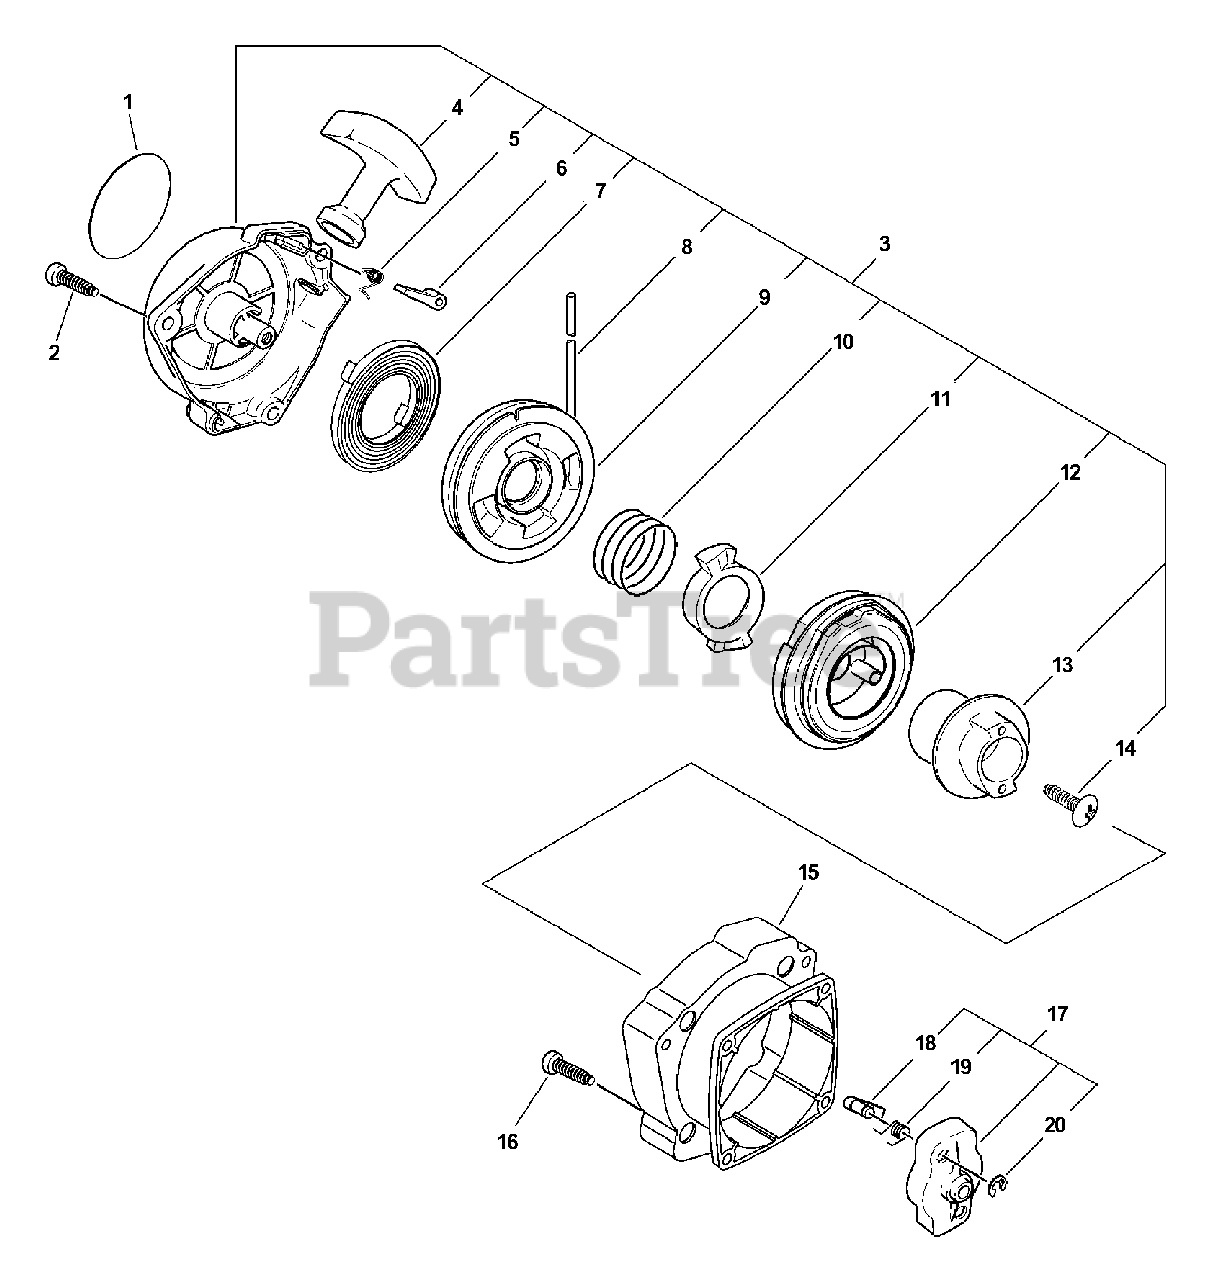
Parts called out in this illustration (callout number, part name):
1	LABEL - EZR
2	SCREW - 5X20 -- TAPPING
3	STARTER ASSY
4	GRIP, STARTER
5	SPRING, PAWL RETURN
6	PAWL, STARTER
7	SPRING, REWIND
8	ROPE, STARTER - 3X800
9	REEL, ROPE
10	SPRING, RETURN
12	SPRING ASSY
13	PLATE, CAM
15	CASE, STARTER
16	SCREW - 4X16
17	STARTER PAWL ASSY
18	PAWL, STARTER
19	SPRING, RETURN
20	RING, RETAINING - 4
